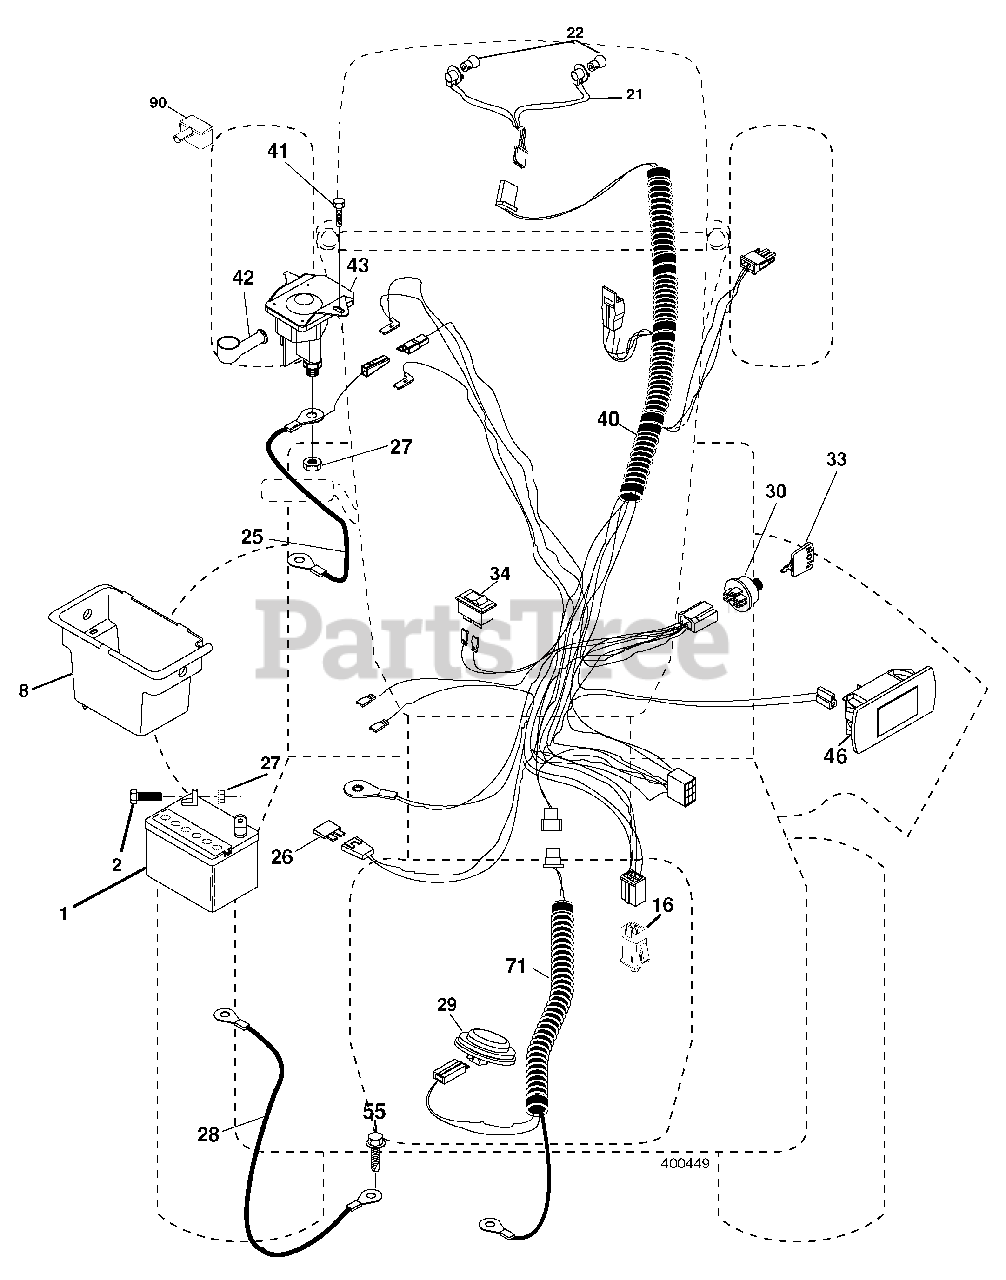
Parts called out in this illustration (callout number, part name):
1	Battery
2	Bolt Hex Head 1/4-20 x 3/4
8	Box Battery
16	Switch Interlock Push-In
21	Harness Socket Light W/4152J
22	Bulb Light
25	Cable Starter
26	Fuse
27	Nut Keps Hex 1/4-20 unc
28	Cable, Ground
29	Switch, Seat
30	Switch, Ignition
33	Key, Ignition
34	Switch Light / Reset
40	Harness Ignition Dash
41	Screw Thd Cut 1/4-20 x 1/2
42	Cover, Terminal
43	Solenoid
46	Gauge SRVCMNDR HRMTR
55	Screw Thdrol 5/16-18 x 3/4 TYTT
71	Harness Ignition
90	Cover Terminal Battery
